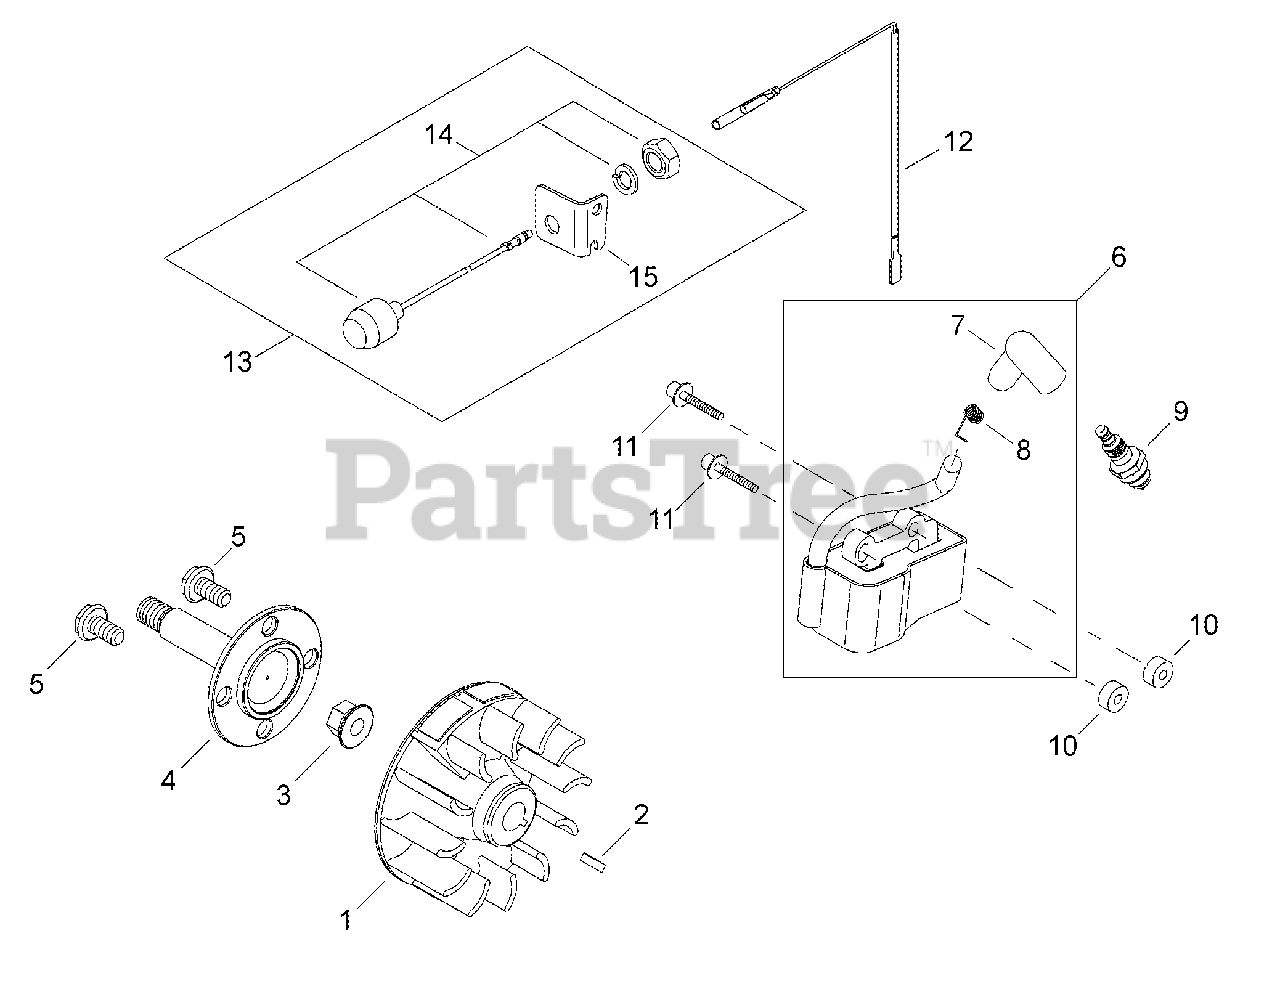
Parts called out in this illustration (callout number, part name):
1	FLYWHEEL
2	KEY - 3X10
3	NUT - 8
4	SHAFT, PUMP
5	BOLT - FLANGE
6	IGNITION COIL ASSY
7	CAP, SPARK PLUG
8	TERMINAL, SPARK PLUG CAP
9	SPARK PLUG -- CMR-5H
10	INSULATOR
11	SCREW - 4X26
12	LEAD - IGNITION
13	IGNITION SWITCH ASSY
14	IGNITION SWITCH ASSY
15	BRACKET
